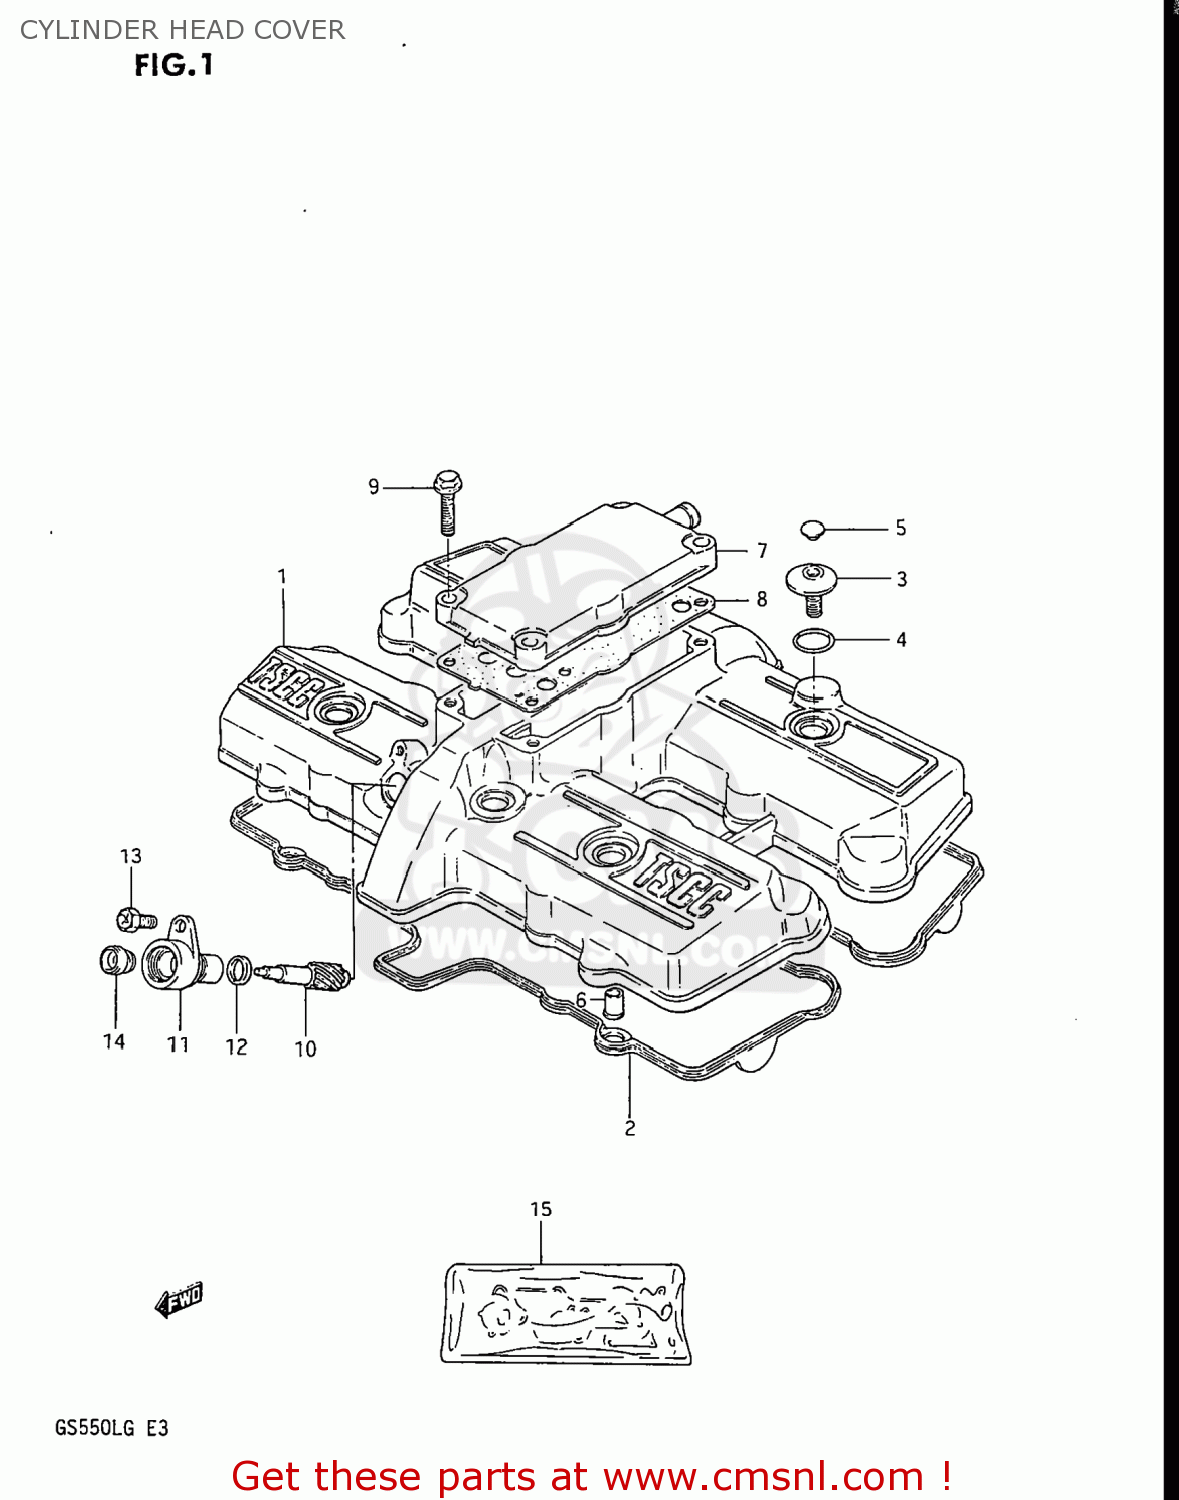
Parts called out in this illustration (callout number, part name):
1	COVER,CYLINDER HEAD
2	GASKET,CYL HEAD COVER (NAS)
3	BOLT(7X5.5)
4	O RING(D:1.9,ID:14.5)
5	CAP(OD:10)
6	PIN
7	COVER,BREATHER
8	GASKET (MCA)
9	BOLT
10	GEAR,TACHOMETER DRIVEN
11	SLEEVE,TACHOMETER DRIVE GEAR
12	SEAL,TACHOMETER DRIVEN
13	SCREW(5X12)
14	SEAL,OIL(5X12X8)
15	GASKET SET (MCA)
